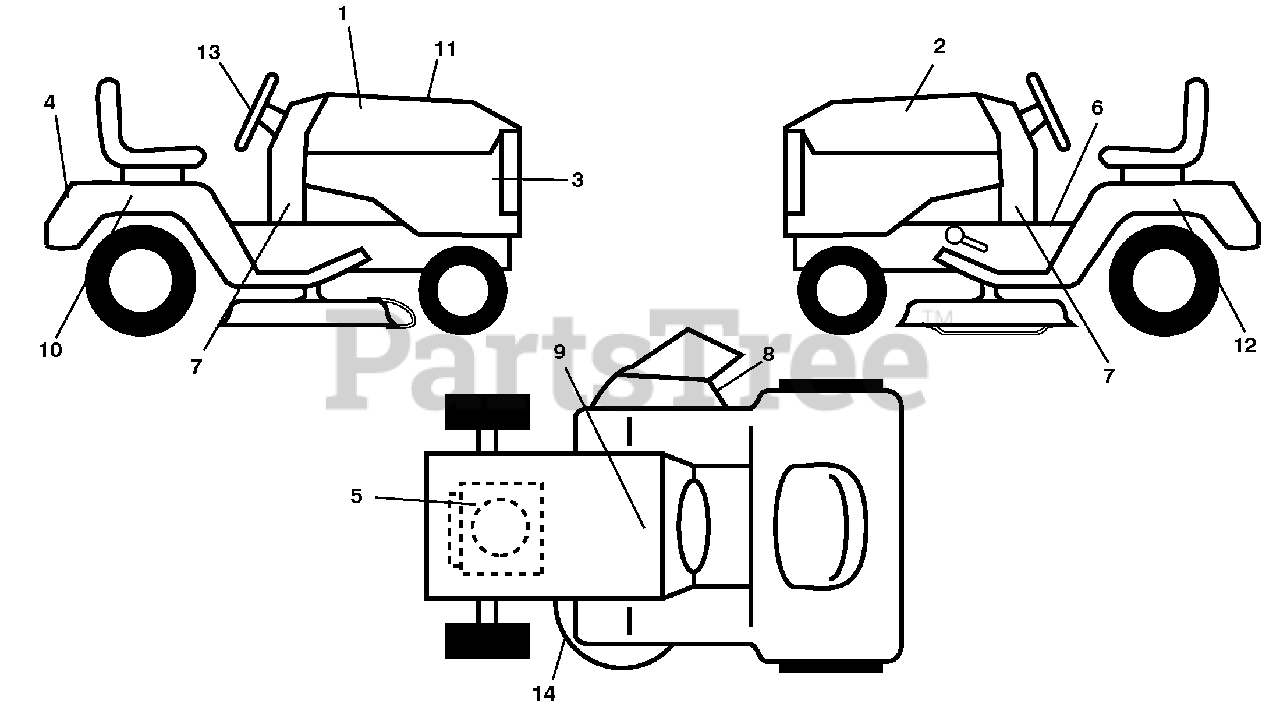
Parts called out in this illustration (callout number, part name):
1	Decal, Hood RH
2	Decal, Hood LH
3	Decal, Side Panel
4	Decal, Fender
5	Decal, Eng H.P.
6	Decal, Fender Operator's
7	Decal, Lower Dash
8	Decal, Warning
9	Decal, Battery Dnge/Poi
10	Decal, Fender SD RH
11	Decal, Replacement
12	Decal, Fender SD LH
13	Decal, Steering Wheel
14	Decal, Mower Schematic
14	Pad, Footrest Control
14	Decal, Bypass
14	Pad, Footrest, LH
14	Manual, Operator's (Eng/French)
14	Manual, Parts (Eng/French)
